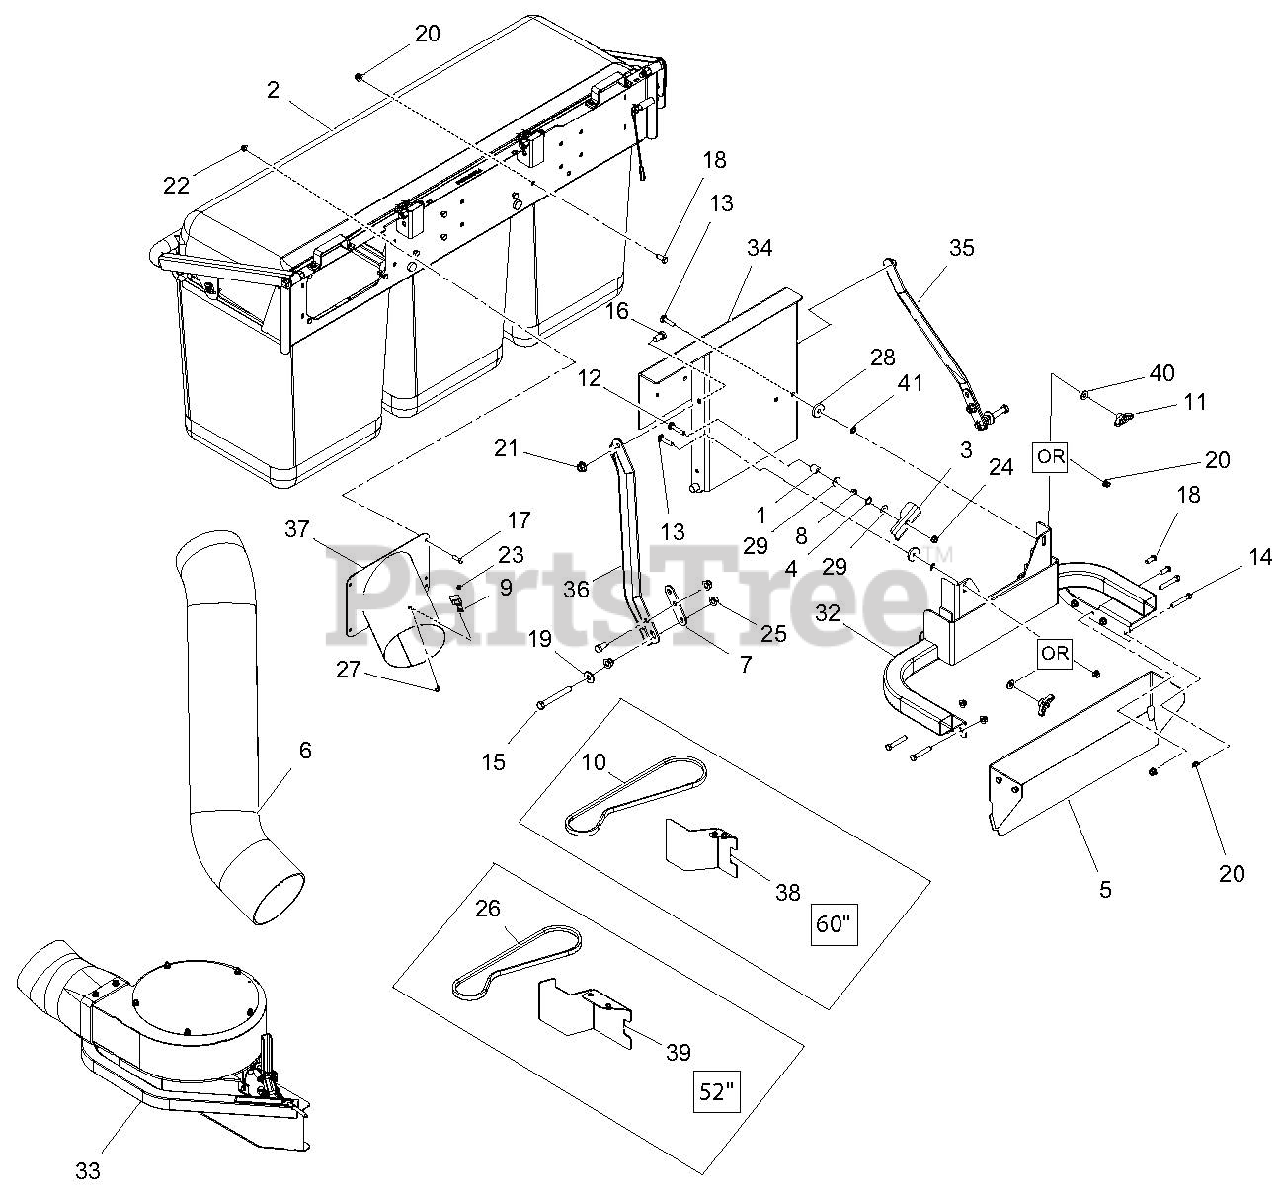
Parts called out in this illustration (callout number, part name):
1	BSHG, SPCR .41 X .75 X .88 PM
2	RECEPTACLE, HUMBOLDT 3-BAG (12BU)
3	LATCH, BAGGER UPPER MOUNT-BLACK
4	WAVE WASHER .640 X .875 X .125 FH
5	SHIELD, HEAT, MUFFLER, BAGGER-BLACK
6	HOSE, BAGGER 7 X 49
7	LINK, OFFSET,BAGGER BRACE-BLACK
8	BSHG, SLV .377X.624X.235
9	LATCH, THUMB
10	V-BELT, 4L WRAPPED CLUTCHING
11	KNOB, WING .38-16 UNC NYL/TALC
12	@BLT-RDHDSQNK .38-16X2.00 G5 Y
13	@BLT-RDHDSQNK .38-16X1.75 G5 YWZC
14	@BLT-HEX .38-16X2.50 GR5 YWZC
15	@BLT-HEX .50-13X4.25 GR5 YWZC
16	@BLT-HEX .50-13X1.00 GR5 YWZC
17	@BLT-HEX .31-18X1.00 GR5 YWZC
18	@BLT-HEX .38-16X1.00 GR5 YWZC
19	@WSHR-FL-STL.563X1.38X.109YWZC
20	NUT-LK-NYL-FLG .38-16 YWZC
21	NUT-LK-NYL-FLG .50-13 YWZC
22	NUT-LK-NYL-FLG .31-18 YWZC
23	@NUT-LK-NYL #10-24 YWZC
24	@NUT, LK-TOP-FLG .38-16 YWZC
25	NUT .50-13 WIZ FLANGE
26	V-BELT, 4L WRAPPED CLUTCHING
27	@SCR-MCH 10-24X.50 HWH YWZC
28	WSHR-FL-STL .406X1.50X.245 YWZC
29	@WSHR-FL-STL.438X1.00X.083 YWZC
32	MOUNT, BAGGER PT200-BLACK
33	BLOWER ASSEMBLY, SERVICE
34	UPPER MOUNT, 3-BAG
35	WLDMT, BAGGER BRACE LH,200/400-BLACK
36	WLDMT, BAGGER BRACE RH,200/400-BLACK
37	ADAPTOR, 200 SERIES INLET-BLACK
38	WLDMT, 60" FRONT BLOWER BAFFLE-BLACK
39	WLDMT, 52" FRONT BLOWER BAFFLE-BLACK
40	@WSHR-FL-STL.438X1.00X.083 YWZC
